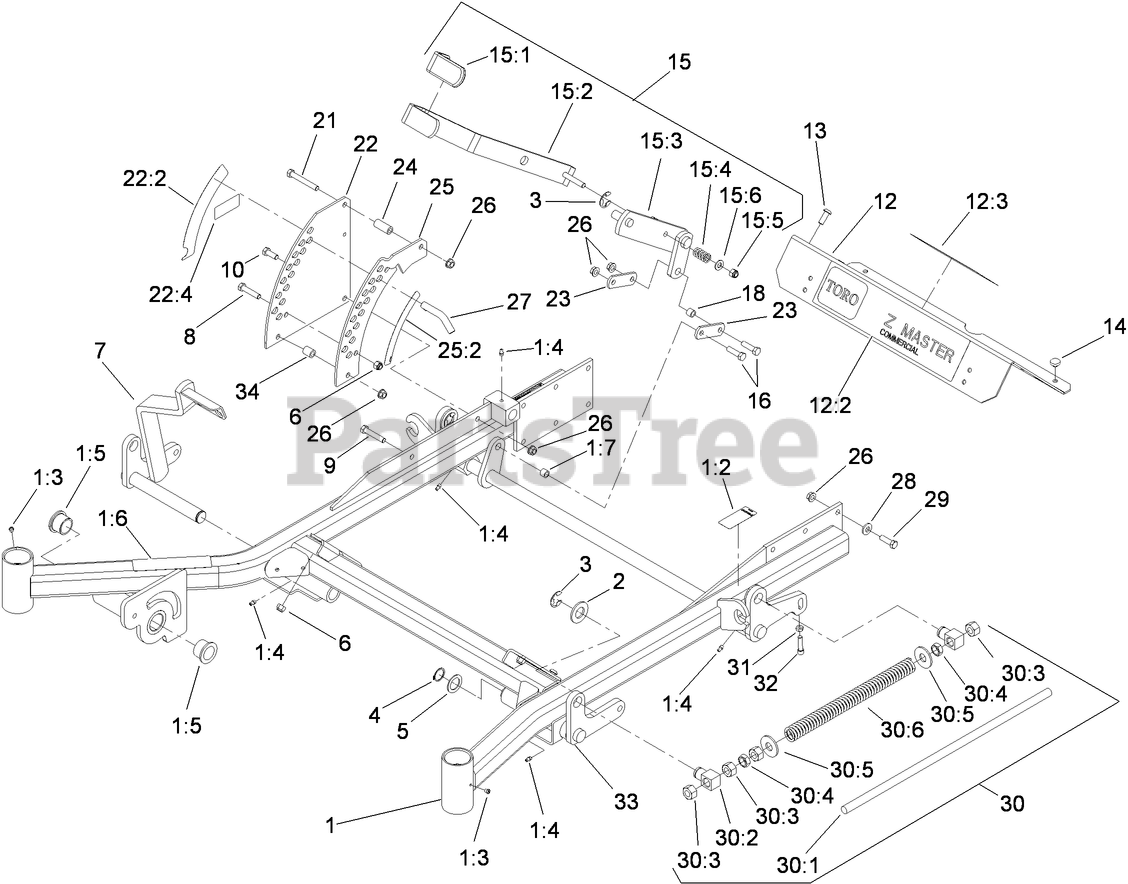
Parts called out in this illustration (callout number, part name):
1	FRAME ASM
1:2	Decal-Brake, Parking
1:4	FITTING-GREASE
1:5	BUSHING
1:6	DECAL-WARNING
1:7	Bushing
2	WASHER-FLAT
3	RING-RETAINING, EXT
4	RING-RETAINING
5	WASHER-SPACER
6	NUT-LOCK, NI
7	LIFT-DECK, RH FRONT
8	SCREW-HH
9	SCREW-HH
10	SCREW-HH
12	FOOTREST
12:3	DECAL-WARNING
13	SCREW-HSBH
14	BUMPER
15	DECK LIFT HANDLE ASM
15:1	GRIP-LEVER, LIFT
15:2	LEVER-LIFT
15:3	ARM-LIFT, DECK
15:4	SPRING-COMPRESSION
15:5	NUT-LOCK, NI
15:6	WASHER-FLAT
16	SCREW-HH
18	Bushing
21	SCREW-HH
22	PLATE-HOC, OUTER
22:2	Decal-Height, Deck
22:4	DECAL-ARRESTER, SPARK
23	ARM-LIFT, DECK
24	BUSHING-LEVER, LIFT
25	PLATE-HOC, INNER
25:2	Decal-Height, Deck
26	NUT-HHF, WHIZ
27	PIN-HOC
28	WASHER-BELLEVILLE
29	SCREW-HH
30	FRONT FRAME SPRING ASM
30:1	ROD-LIFT, DECK
30:2	SWIVEL-DECK MOUNT, REAR
30:3	NUT-HEX
30:4	NUT-JAM
30:5	WASHER-FLAT
30:6	SPRING-SUPPORT, DECK
31	NUT-JAM
32	SCREW-HSH
33	LIFT-DECK, LH
34	BUSHING-LEVER, LIFT
